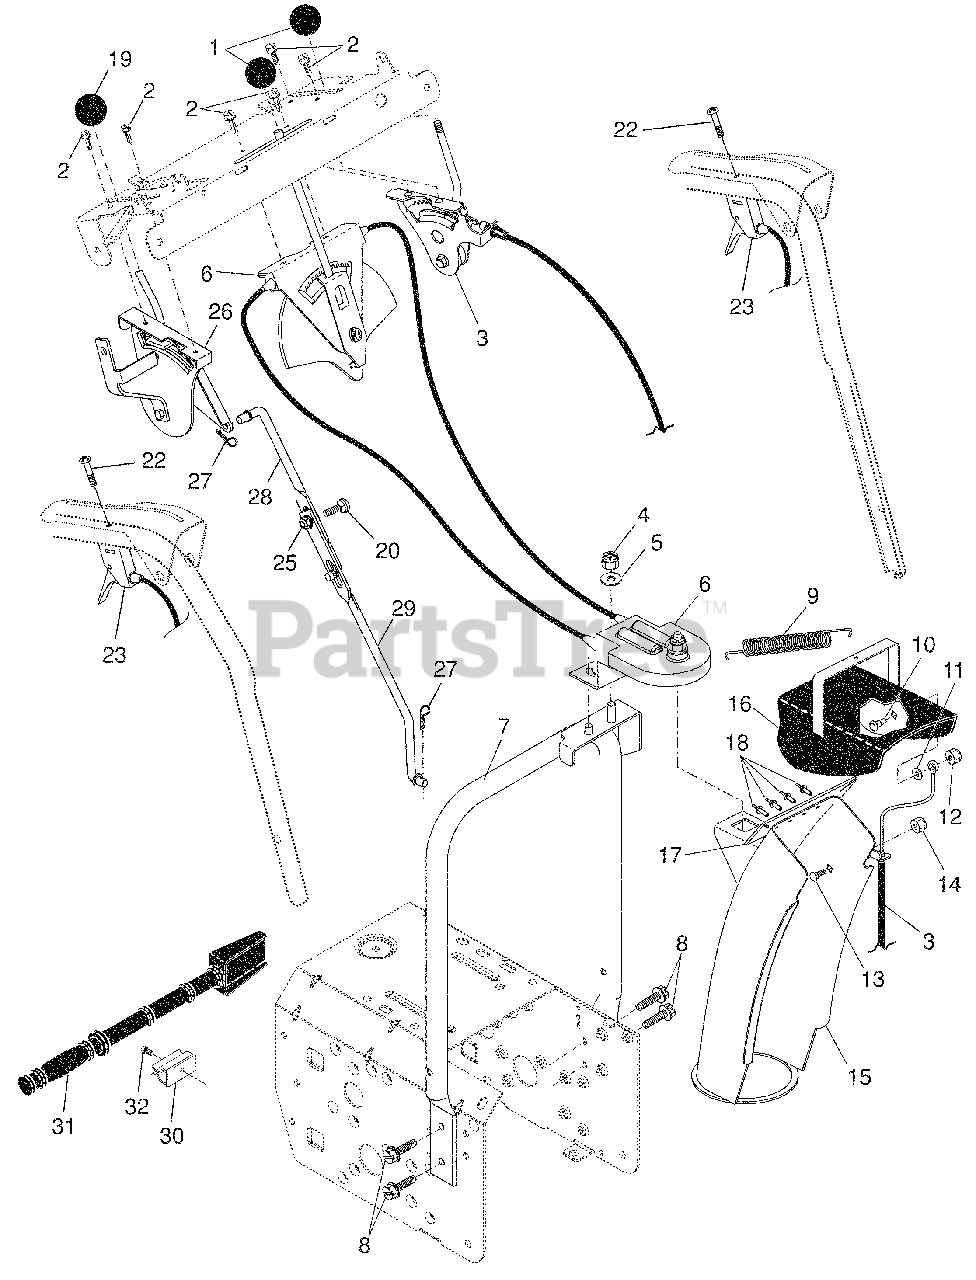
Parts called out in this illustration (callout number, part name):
1	Knob, Lever
2	Screw #10-24 x 5/8
3	Control Assembly, Deflector
4	Nut, Lock 3/8-16
5	Washer, Flat 3/8
6	Control Assembly, Chute Rotater
7	Support, Pivot
8	Screw, Hex Head 5/16-18 x 3/4
9	Spring, Deflector
10	Bolt, Shoulder
11	Washer, Friction, Nylon
12	Nut, Lock 1/4-20
13	Bolt, Carriage 5/16-18
14	Nut, Lock 5/16-18
15	Chute Assembly
16	Deflector Assembly
17	Seal, Deflector
18	Rivet, Blind
19	Knob, Speed Control Lever
20	Bolt, Carriage 5/16-18 x 3/4
22	Screw #10-24 x 1-1/2
23	Control Assembly, Power Steering
25	Nut, Lock 5/16-18
26	Lever Assembly, Speed Control
27	Retainer, Hairpin
28	Rod, Upper, Speed Control
29	Rod, Lower, Speed Control
30	Clamp, Clean-Out Tool
31	Tool, Clean-Out
